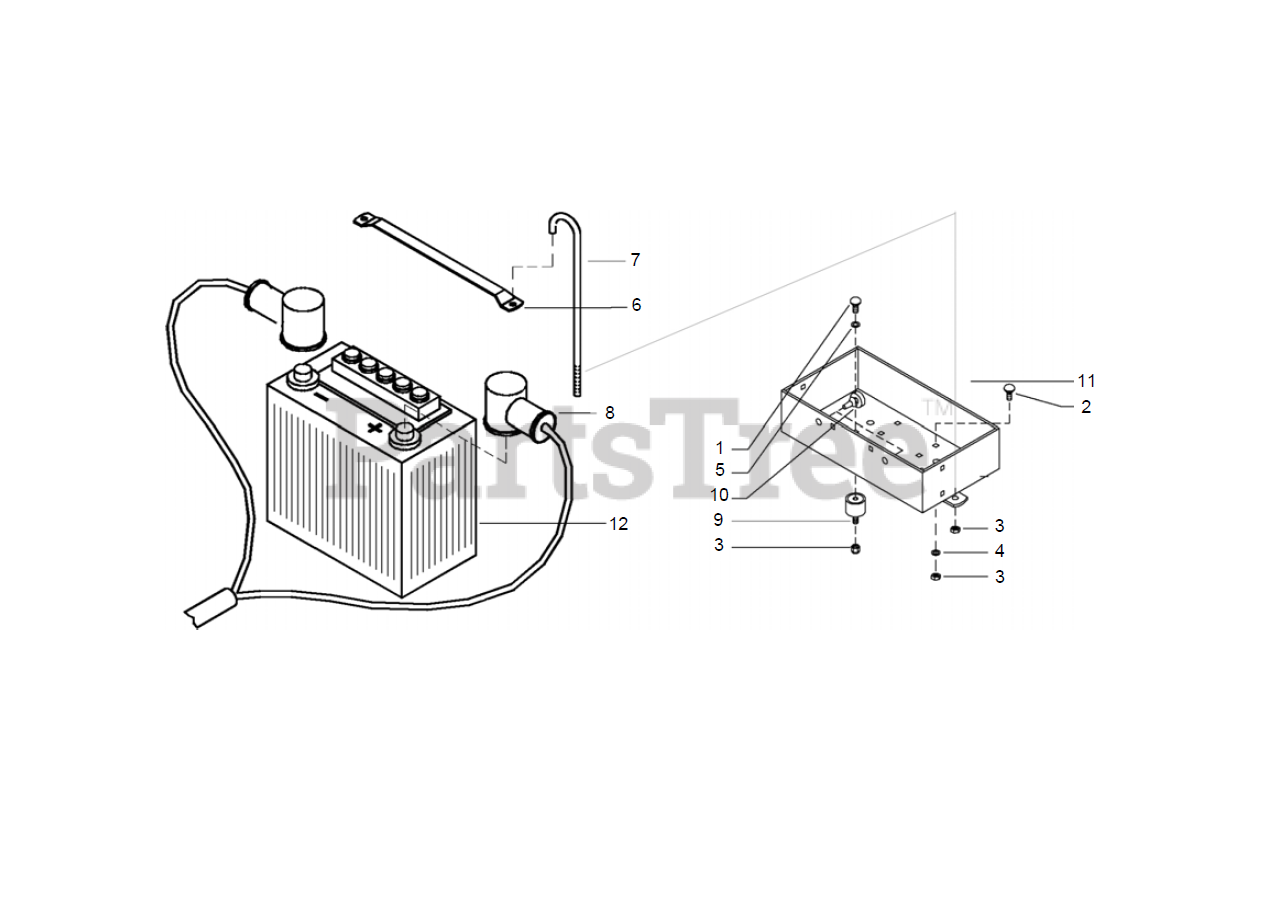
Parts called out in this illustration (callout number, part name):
1	BOLT W/SQUARE NUT M6X12
2	BOLT M6X16
3	LOCKNUT M6 STANDARD
4	WASHER, FLAT M6 4X12
5	WASHER, FLAT M9X24
6	BRACKET, BATTERY
8	CABLE, ELECTRIC STARTER
9	RUBBER BUFFER,VIBRATION DAMPER
10	RUBBER STOPPER
11	BOX, BATTERY
12	BATTERY, 12V 14:16Ah
